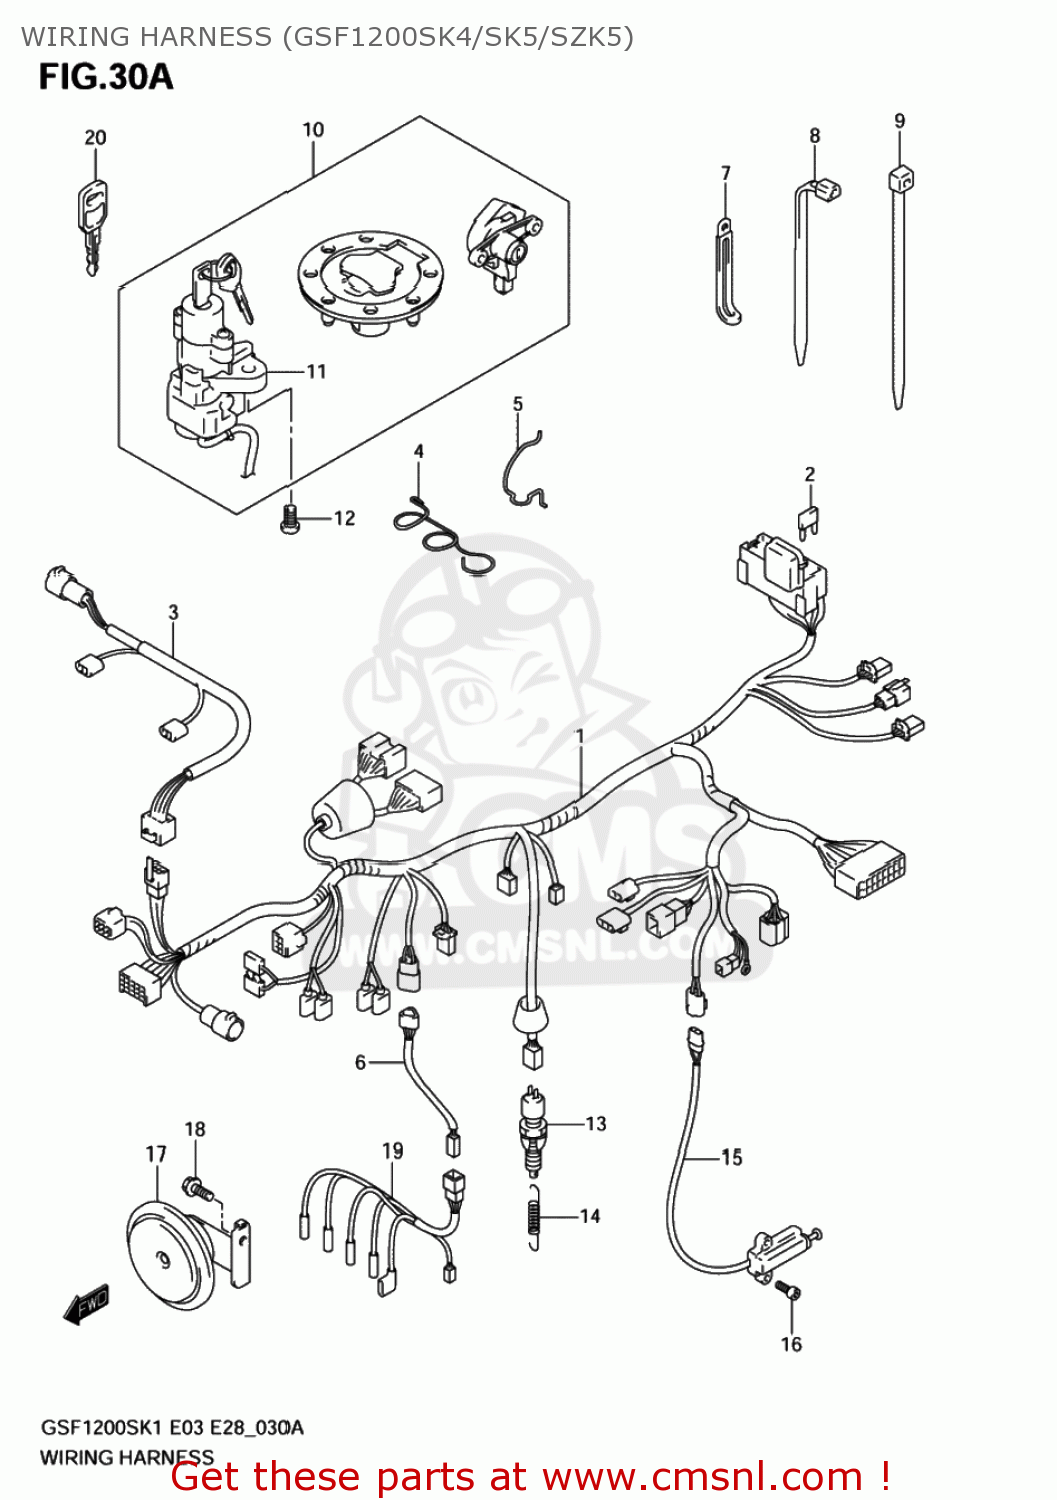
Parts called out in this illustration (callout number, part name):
1	HARNESS,WIRING
2	FUSE(10A)
3	HARNESS,WIRING NO.2
4	GUIDE,WIRING HARNESS
5	GUIDE,WIRING HARNESS
6	WIRE,TPS LEAD
7	CLAMP(L:45)
8	CLAMP(L:90)
9	CLAMP(L:145)
10	LOCK SET
11	LOCK ASSY,STEERING
12	BOLT(8X20)
13	SWITCH ASSY,STOP LAMP
14	SPRING
15	SWITCH ASSY,SIDE STAND
16	BOLT
17	HORN ASSY
18	BOLT
19	WIRE,CARB HEATER LEAD
20	KEY,BLANK
